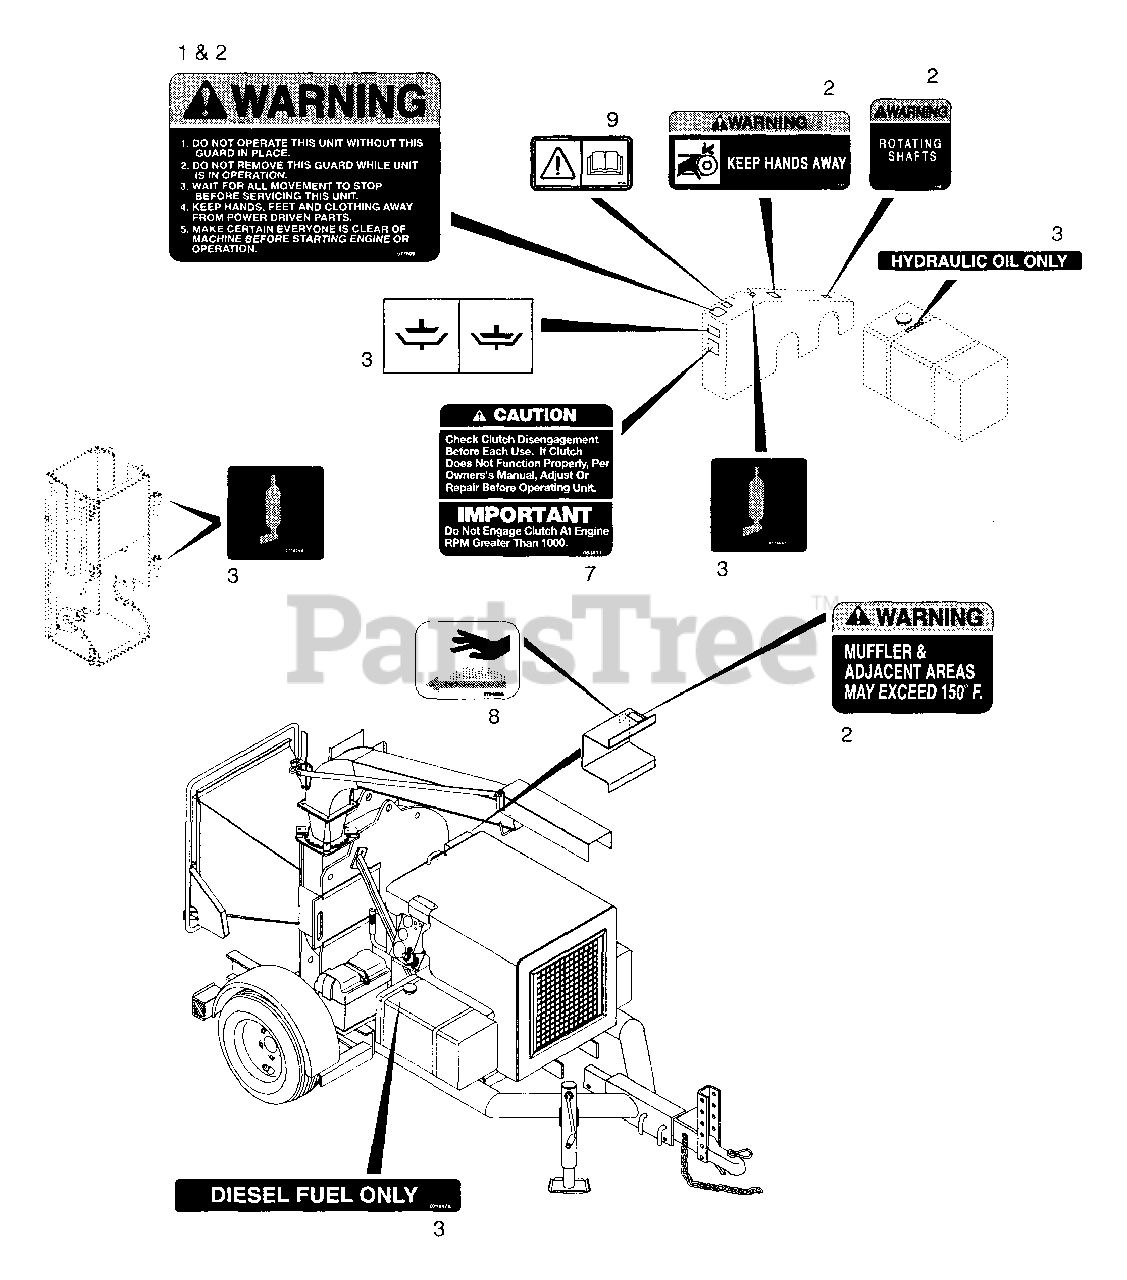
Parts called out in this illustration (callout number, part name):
1	Decal-Set
2	Decal-Set Large Chippers
3	Decal-Set Chipper Black/White
7	Decal-Clutching Instruction
8	Decal-Hot Surface Symbol
9	Decal-Set Chipper CE
